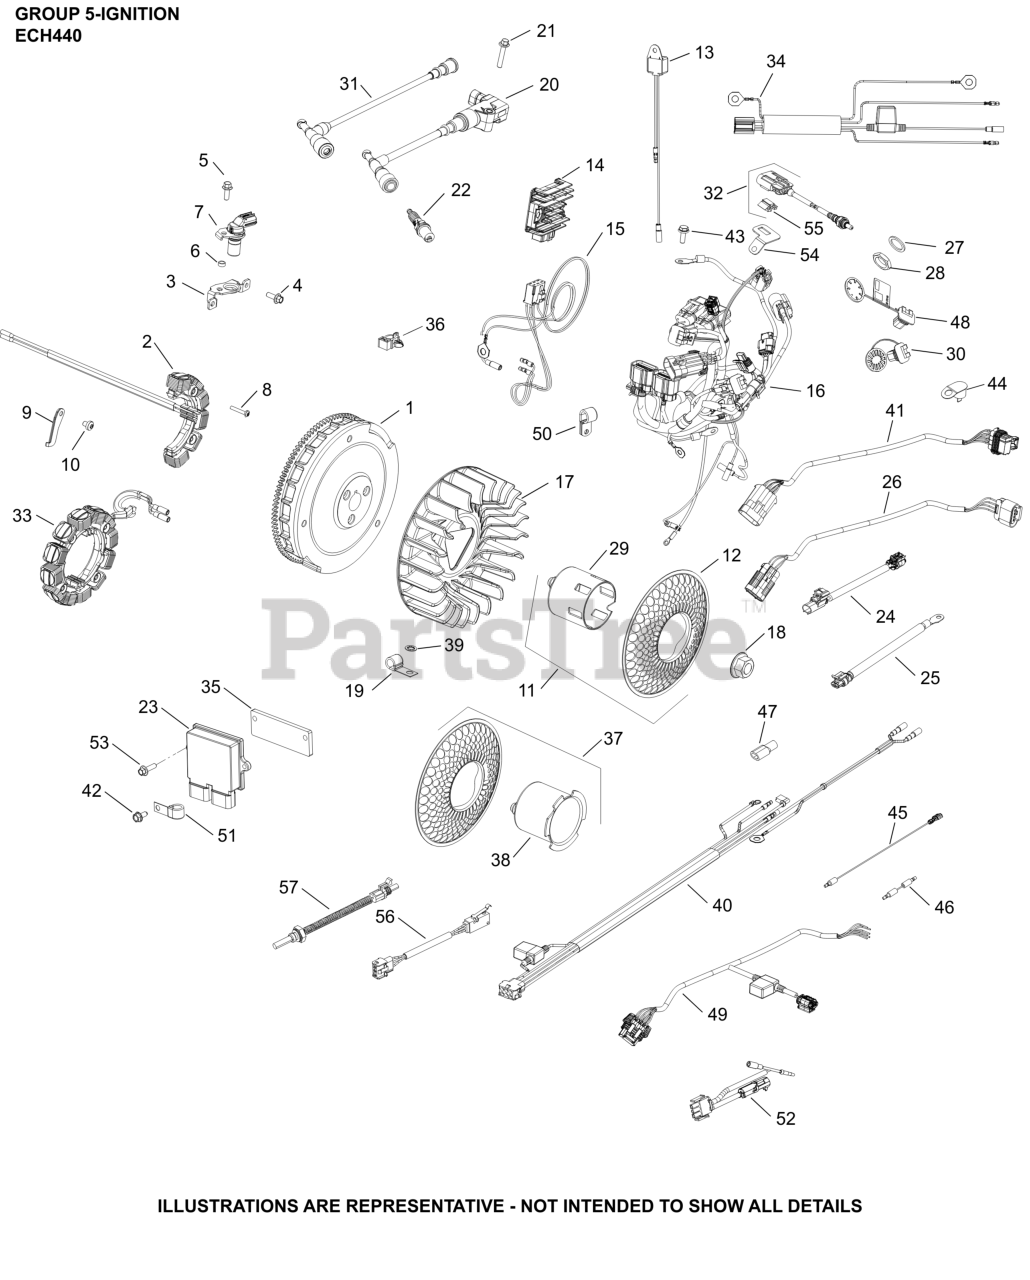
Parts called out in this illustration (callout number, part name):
1	FLYWHEEL ASSY, ELECTRIC START 18 AMP
3	BRACKET, CRANK SENSOR
5	SCREW, HEX FLANGE
7	SENSOR, SPEED
16	HARNESS, WIRING ASSY
17	FAN, FLYWHEEL
18	NUT, FLYWHEEL
20	COIL, IGNITION - EFI
21	SCREW, HEX FLANGE (M6)
22	PLUG, SPARK
29	CUP, STARTER DRIVE
30	CAP, CONNECTOR (4-WAY, BLACK)
42	SCREW, HEX FLANGE (M6)-USE 25 086 433-S
43	SCREW, M6 X 16
50	CLAMP, INSULATED
NI	LEAD, SENSOR TEMPERATURE
NI	MODULE, ECU
